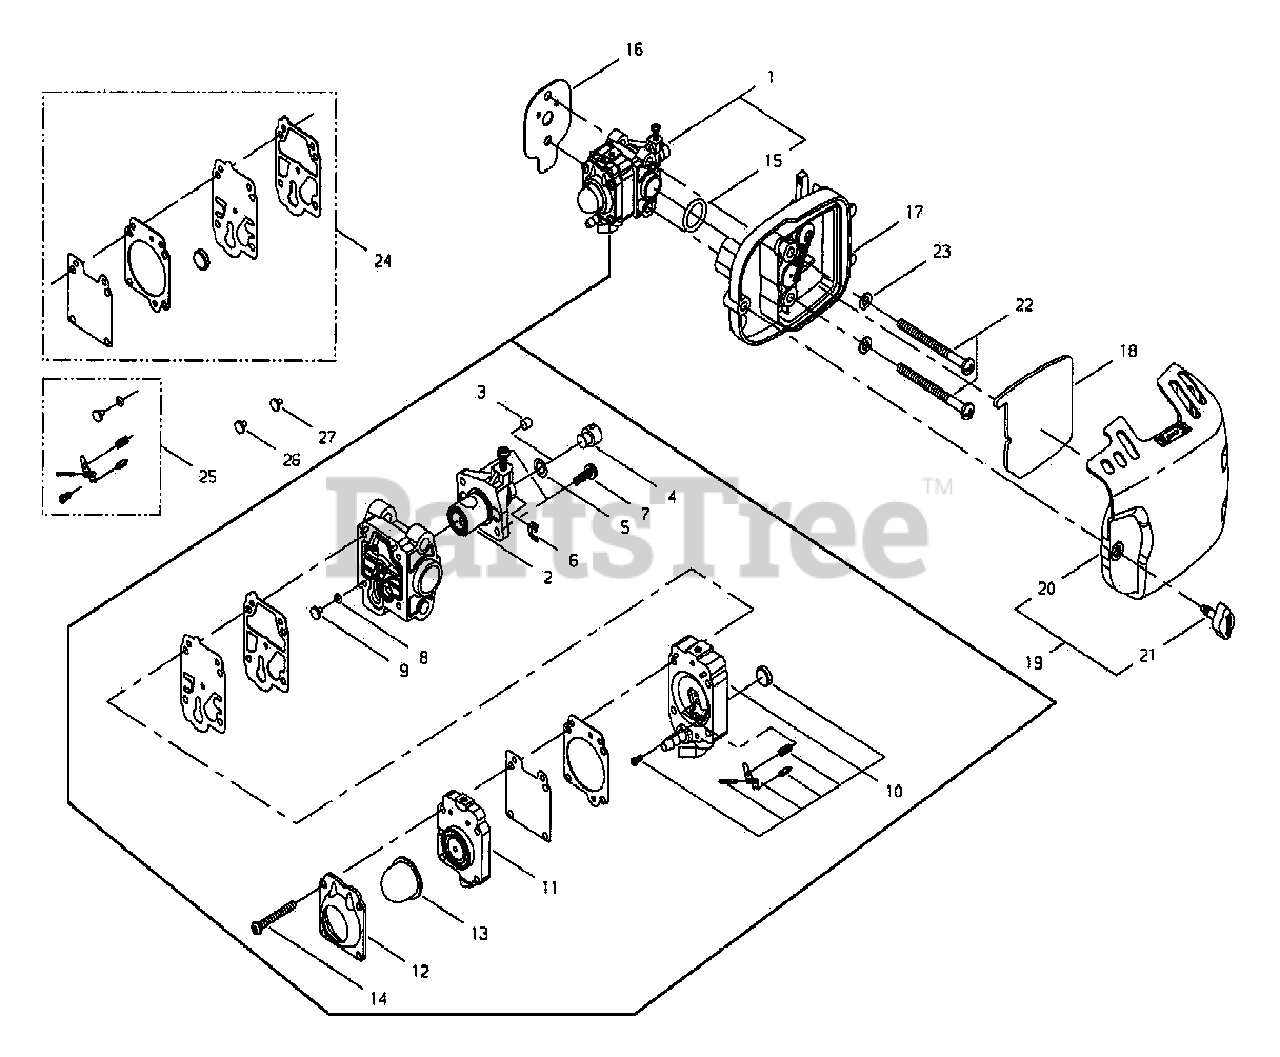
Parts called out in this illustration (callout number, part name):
1	CARBURETOR
2	THROTTLE VALVE ASSY
3	PLUG
4	SWIVEL
5	WASHER
6	RING, RETAINING
7	SCREW
8	O-RING
9	JET, MAIN
10	PUMP BODY ASSY
11	BASE, PURGE
12	RETAINER, PURGE BULB
13	BULB, PURGE
14	SCREW, PUMP COVER
15	O-RING - 15
16	GASKET
17	CASE, AIR FILTER
18	FILTER, AIR
19	AIR FILTER COVER ASSY
20	COVER, AIR FILTER
21	THUMBSCREW
22	SCREW - 5X60
23	WASHER - 5
24	DIAPHRAGM/GASKET KIT
25	INLET NEEDLE VALVE KIT
26	JET, MAIN - 2000M
27	JET, MAIN - 2000M
